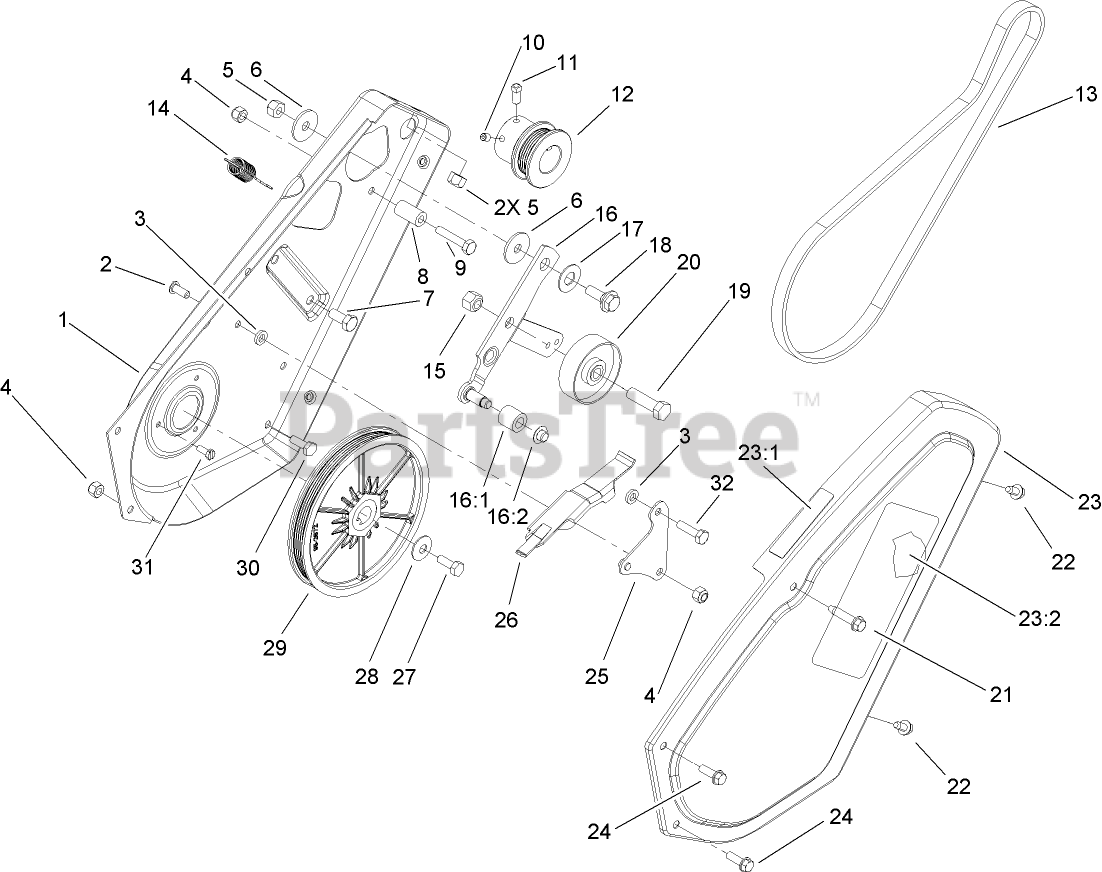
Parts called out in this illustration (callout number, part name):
1	PLATE-SIDE, LH
2	SCREW-HSBH
3	SPACER-PLATE, PIVOT
4	NUT-LOCK, NI
5	NUT-LOCK, NI
6	WASHER-PIVOT
7	SCREW-HH
8	SLEEVE-GUIDE, BELT
9	SCREW-HH
10	SCREW-HSH
11	SCREW-SQH
12	PULLEY-ENGINE
13	BELT-DRIVE
14	SPRING-EXTENSION
15	NUT-LOCK, CONE
16	IDLER ARM ASM
16:1	ROLLER-BRAKE
16:2	NUT-PUSH
17	WASHER
18	SCREW-SHOULDER
19	SCREW-HH
20	PULLEY-IDLER
21	SCREW-HWH, TAP
22	SCREW
23	COVER-DRIVE
23:1	DECAL-WARNING
23:2	DECAL
24	SCREW-HWH
25	PIVOT PLATE ASM
26	BRAKE-ARM
27	SCREW-HH
28	WASHER-BELLEVILLE
29	PULLEY ROTOR ASM
30	SCREW-HH
31	SCREW-SHH
32	SCREW-HH
